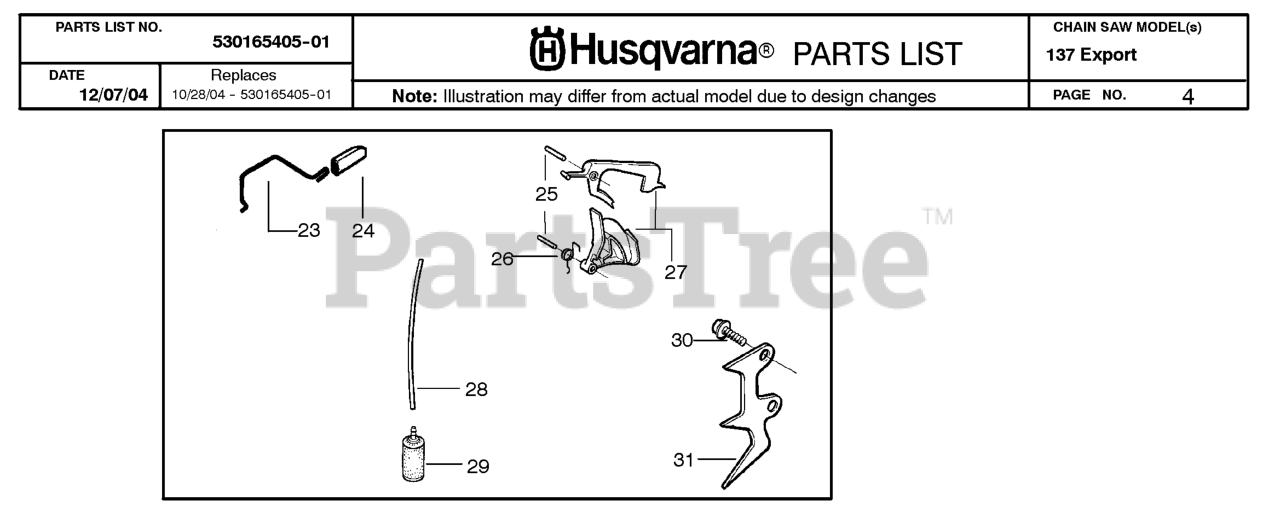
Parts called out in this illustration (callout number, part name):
23	THROTTLE SHAFT 36/41
24	THROTTLE ACTUATOR 36/41
25	PIN,TRIGGER 36/41
26	TRIGGER SPRING 36/41
27	THROTTLE TRIGGER-KIT
28	HOSE. FUEL
29	FUEL PICK-UP
31	SPIKE 36/41
